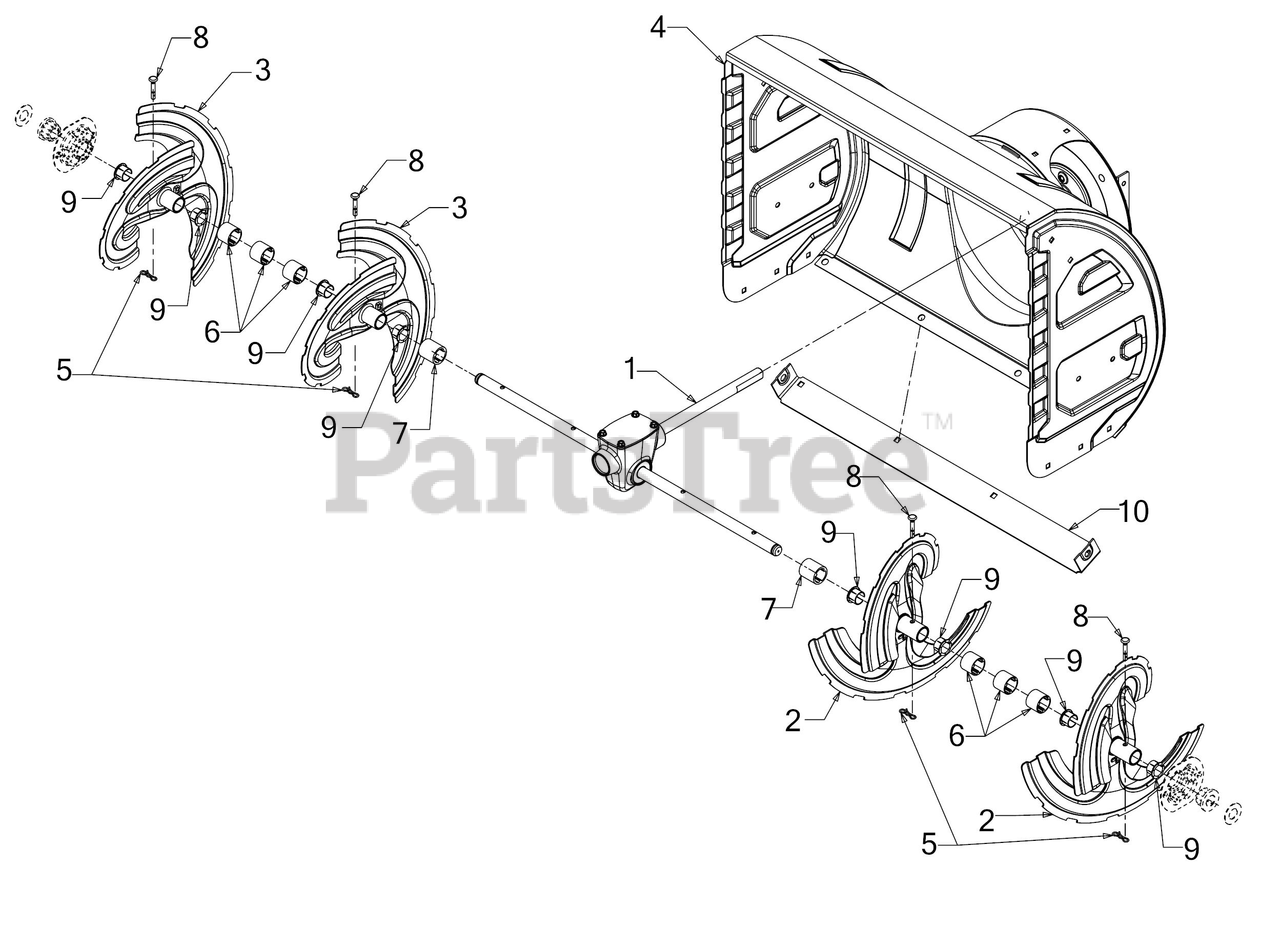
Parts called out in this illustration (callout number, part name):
1	28" AUGER GEARBOX ASSEMBLY
2	10T SPIRAL (LH)
3	10T SPIRAL (RH)
5	BOW TIE COTTER PIN 1/4-5/16
6	SPACER 1.25OD x .75ID X1.00 LG
7	SPACER 1.25OD x .75ID x 1.312 LG
8	SHEAR PIN .25 x 1.50 GR2
8	Cub Cadet SHEAR PINS (2X SNOW)
8	SHEAR PINS QTY 4
9	FLANGE BUSHING
